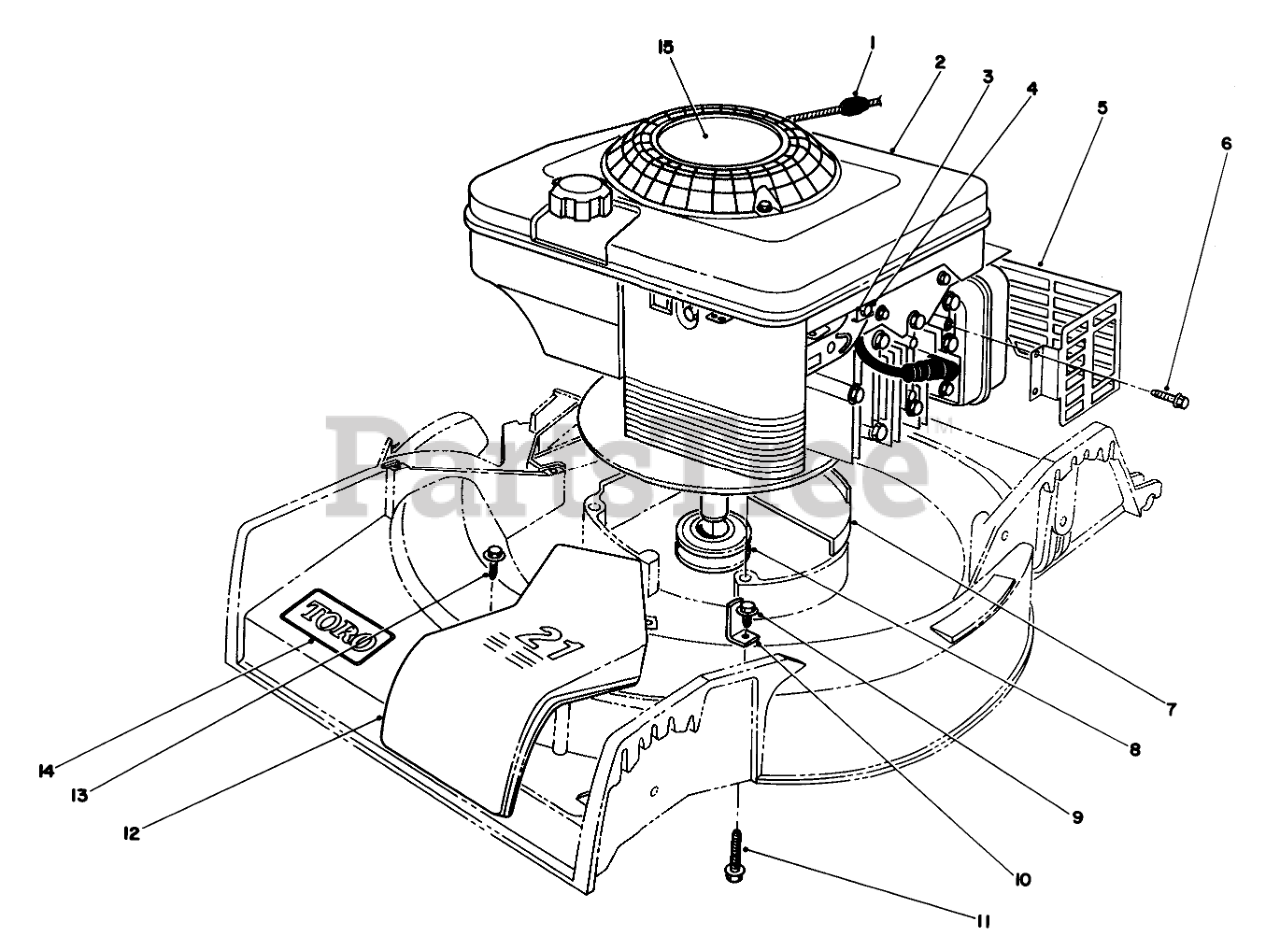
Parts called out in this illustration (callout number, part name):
1	STOP-ROPE
3	CLAMP-CASING
4	Screw
5	SHIELD-MUFFLER
6	SCREW-HWH
7	HOUSING CAP
8	PULLEY-DRIVER
9	SCREW-HWHTF
10	BELT GUIDE
11	THD FORM SCREW
12	BELT COVER 21" S D
13	SCREW-HWH
14	DECAL
15	DECAL - ENGINE
